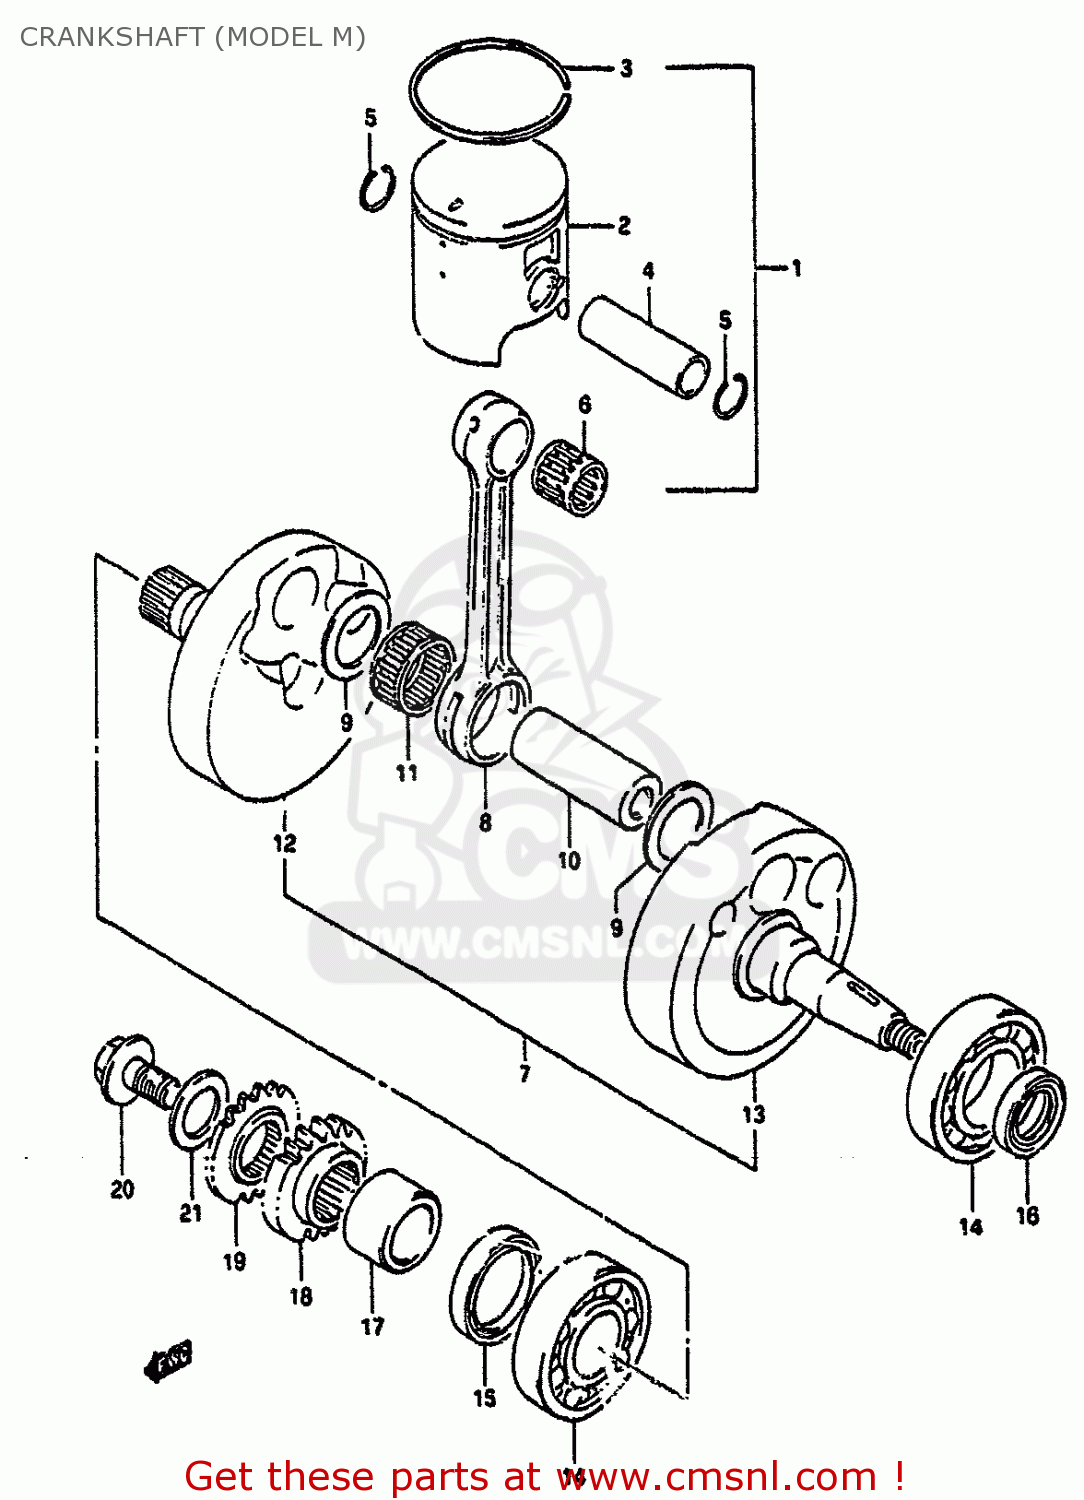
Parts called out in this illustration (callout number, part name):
1	PISTON KIT
2	PISTON
3	RING,PISTON
4	PIN,PISTON
5	CIRCLIP
6	BEARING(15X19X20)
7	CRANKSHAFT ASSEMBLY
8	ROD,CONNECTING
9	WASHER
10	PIN,CRANK
11	BEARING(22X28X16)
12	CRANKSHAFT
13	CRANKSHAFT,LEFT
14	BEARING
15	SEAL,OIL(30X40X7)
16	SEAL,OIL(18X30X6)
17	SEAL,OIL(18X30X6)
18	GEAR,PRIMARY DRIVEN
19	O RING(D:2.4,ID:19.8)
20	GEAR,PRIMARY DRIVEN
21	WASHER
22	NUT
23	WASHER
